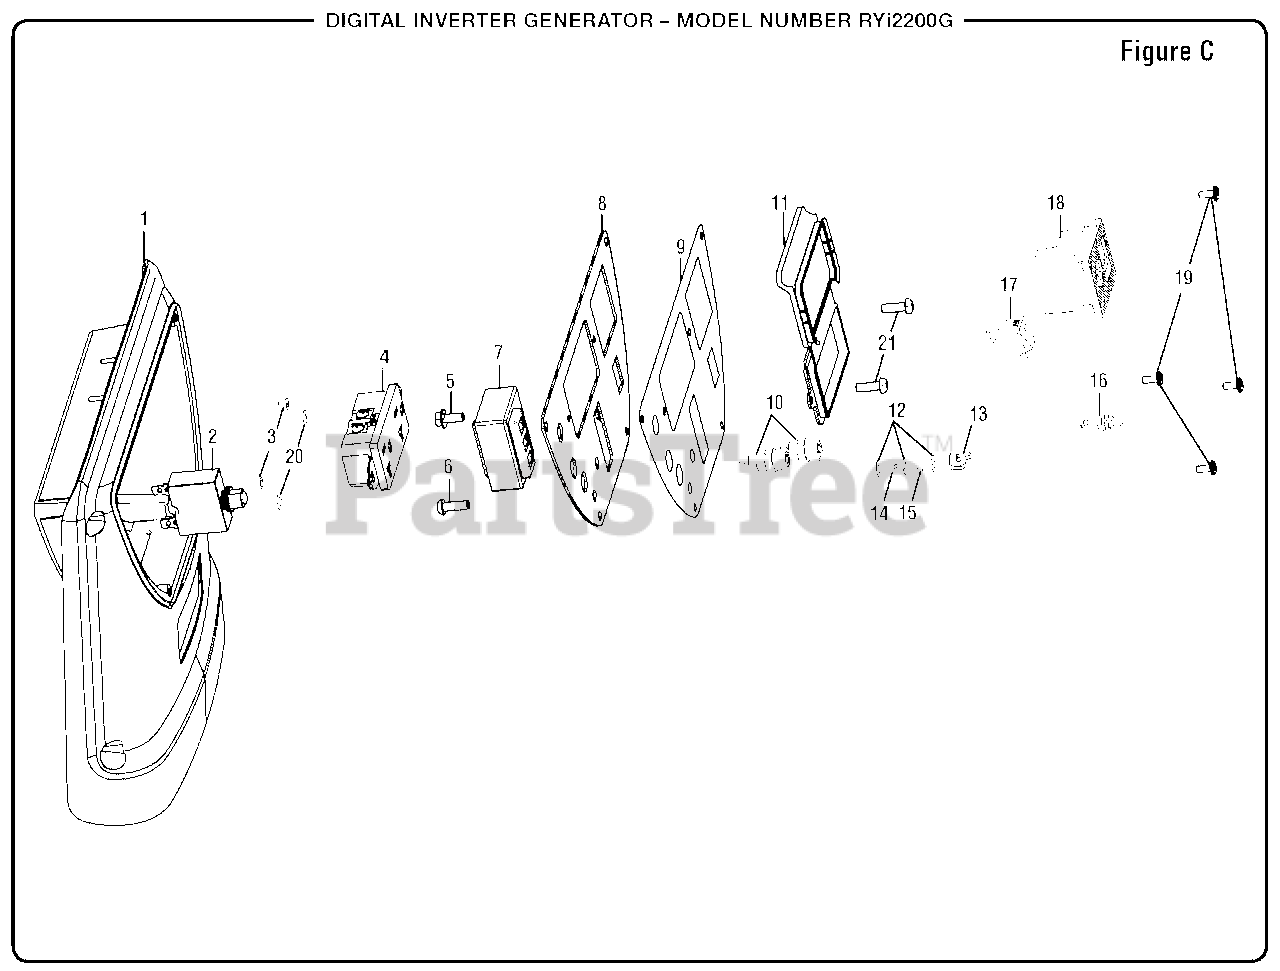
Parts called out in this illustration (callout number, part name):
1	Front Cover
2	Circuit Breaker (20 Amp)
3	Flange Nut (M4)
4	120 Volt Duplex Receptacle
5	Bolt (#10 x 12 mm, Flanged Hd.)
6	Screw (M5 x 16 mm, Phillips Pan Hd.)
7	Ignition Module
8	Control Panel
9	Front Panel Label
10	Connector
11	120 Volt Outlet Cover
12	Washer (M5 x 10 mm x 0.5t)
13	Wing Nut (M5)
14	Hex Nut (M5)
15	Lock Washer (OD9 x ID5 x 1.3t)
16	Reset Button
17	Intelligent Switch
18	Receptacle DC
19	Screw w/Washer (M4 x 10 mm, T20 Torx Button Hd.)
20	Washer (OD8 x ID4.3 x 0.5t)
21	Screw (M4 x 10 mm, Phillips Pan Hd.)
